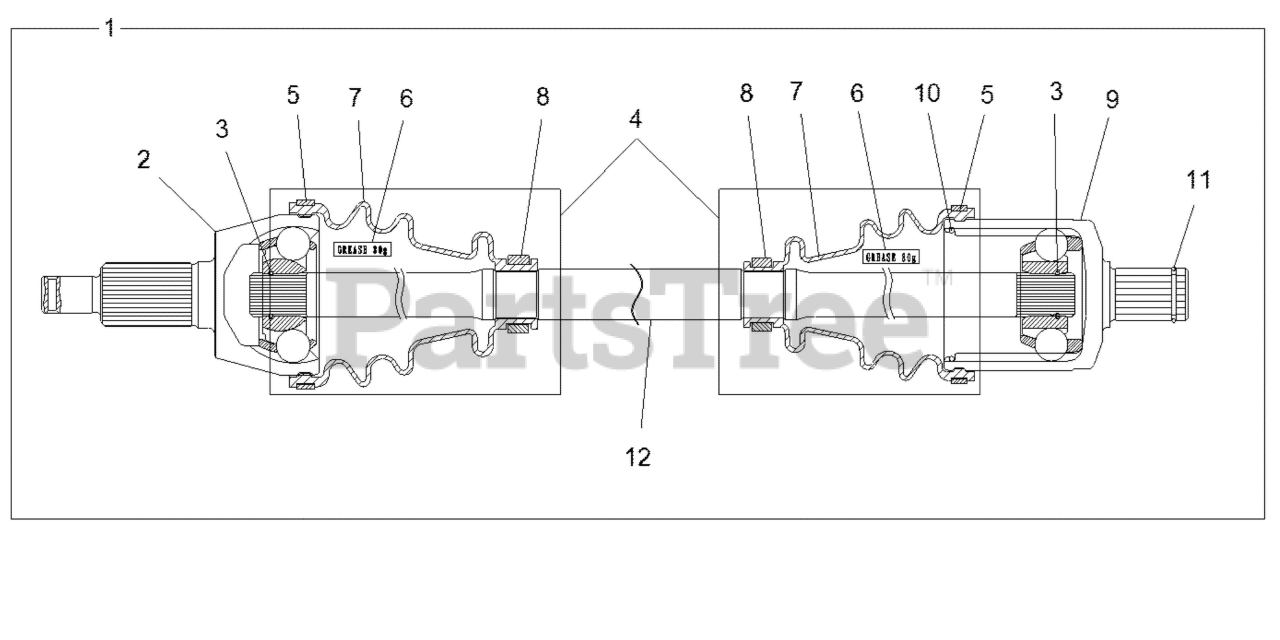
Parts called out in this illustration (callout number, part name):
1	ASM-HALF SHAFT,FRONT,LT
2	JOINT-CV,OUTER
3	CIRCLIP-1.8X22.2(PR-3011)
4	KIT-BOOT,PLUNGING JNT(PR-8062)
5	CLAMP-LARGE(PR-2019)
6	GREASE(K575/VW738)
7	BOOT(PR-0015)
8	CLAMP-SMALL(PR-0016)
9	JOINT-CV,INNER
10	CIRCLIP-2.0X61.7(PR-2016)
11	CIRCLIP-1.6X24.4(PR-2025)
12	SHAFT,23.5(PR-315)
